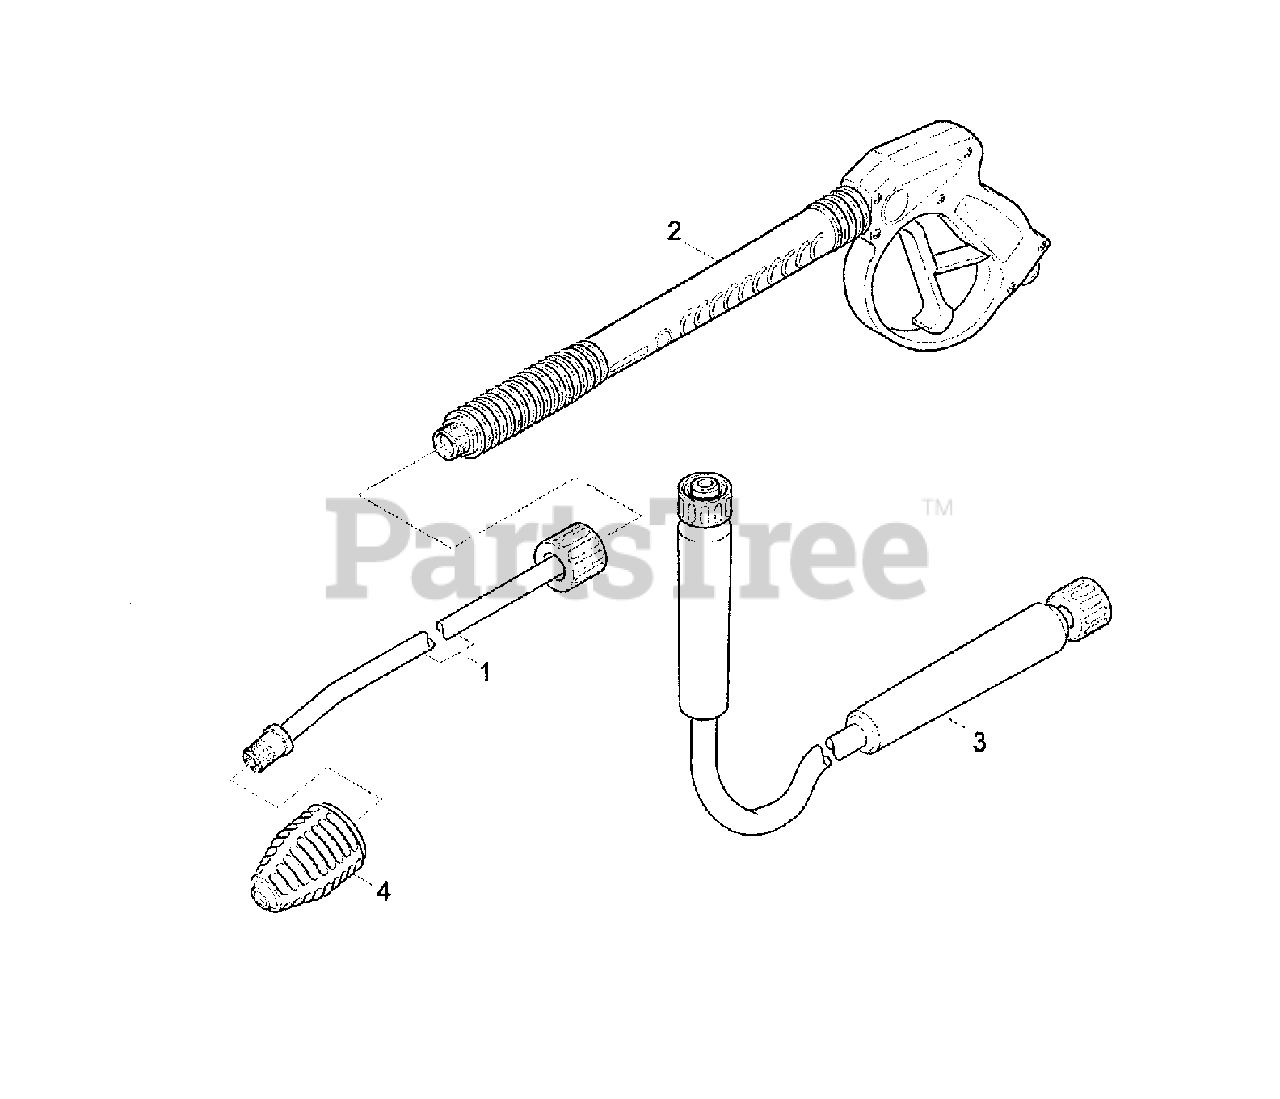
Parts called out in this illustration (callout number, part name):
2	Trigger Gun
3	High Pressure Hose
4	Rotary Nozzle
